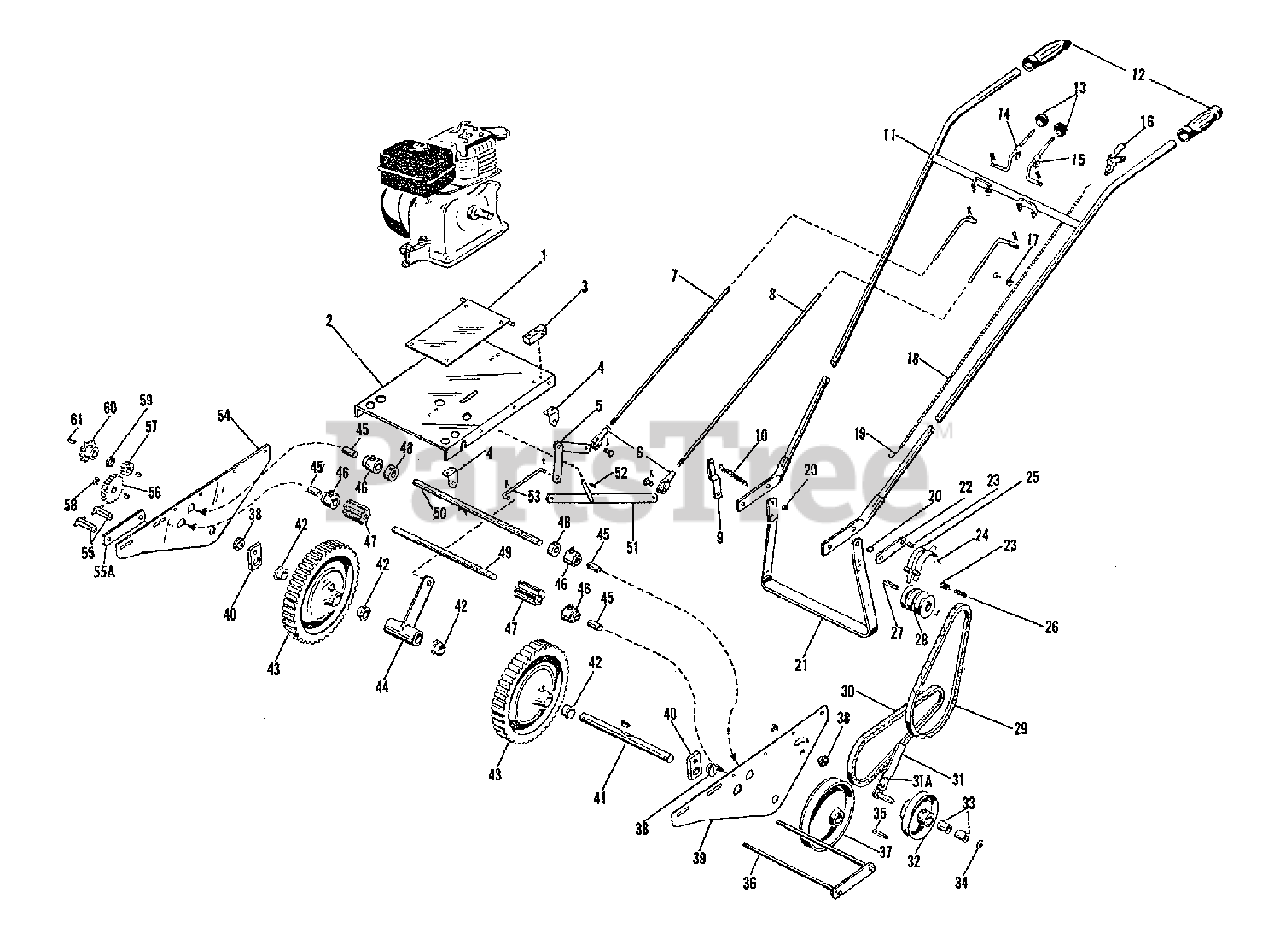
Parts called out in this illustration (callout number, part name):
1	PLATE ASSEMBLY, Engine Pivot
2	DECK, Frame
3	PIVOT BLOCK, Engine
4	BRACKET, Lever
5	LEVER ASSEMBLY, Wheel Clutch
6	END ASSEMBLY, Rod
7	CLUTCH ROD, Wheel
8	CLUTCH ROD, Engine
9	SPRING CLIP, Stand
10	SPRING, Stand
11	HANDLE ASSEMBLY
12	GRIP, Rubber
13	BALL, Clutch Lever
14	LEVER ASSEMBLY, Clutch
15	LEVER ASSEMBLY, Engine Clutch
16	LEVER ASSEMBLY, Throttle Control
17	CLAMP, Cable
18	CABLE, Throttle
19	WIRE, Throttle
20	BUSHING, Stand
22	HOLDER, Belt Stop
24	STOP ASSEMBLY, L.H. Belt
25	STOP ASSEMBLY, R.H. Belt
26	HOLDER STUD, Belt Stop
27	KEY, Engine Pulley
28	PULLEY, Engine
29	BELT, "V" 31"
30	BELT, "V" 27"
31	LEVER ASSEMBLY, Countershaft
32	PULLEY ASSEMBLY, Countershaft
33	BEARING, Countershaft Pulley
35	KEY, Pulley
36	CLAMP ASSEMBLY, Hitch
37	PULLEY, Drive
38	BUSHING, Flange
39	SIDE MEMBER, L.H. Frame
40	CRANK, Axle
42	BUSHING, Wheel
43	WHEEL & TIRE ASSEMBLY
44	LEVER ASSEMBLY, Axle
45	BUSHING, Bearing
47	DRIVE PINION, Wheel
48	COLLAR, Set
49	SHAFT, Wheel Pinion
50	SHAFT, Pulley
51	LEVER ASSEMBLY, Engine Lift
52	PIN, Engine Lift Rod
53	LEVER LINK, Wheel Clutch
54	SIDE MEMBER, R.H. Frame
55	NUT, Hitch Clamp
55A	BAR, Hitch Clamp
58	RING, Retaining
59	SPACER, Sprocket
61	KEY, Sprocket
